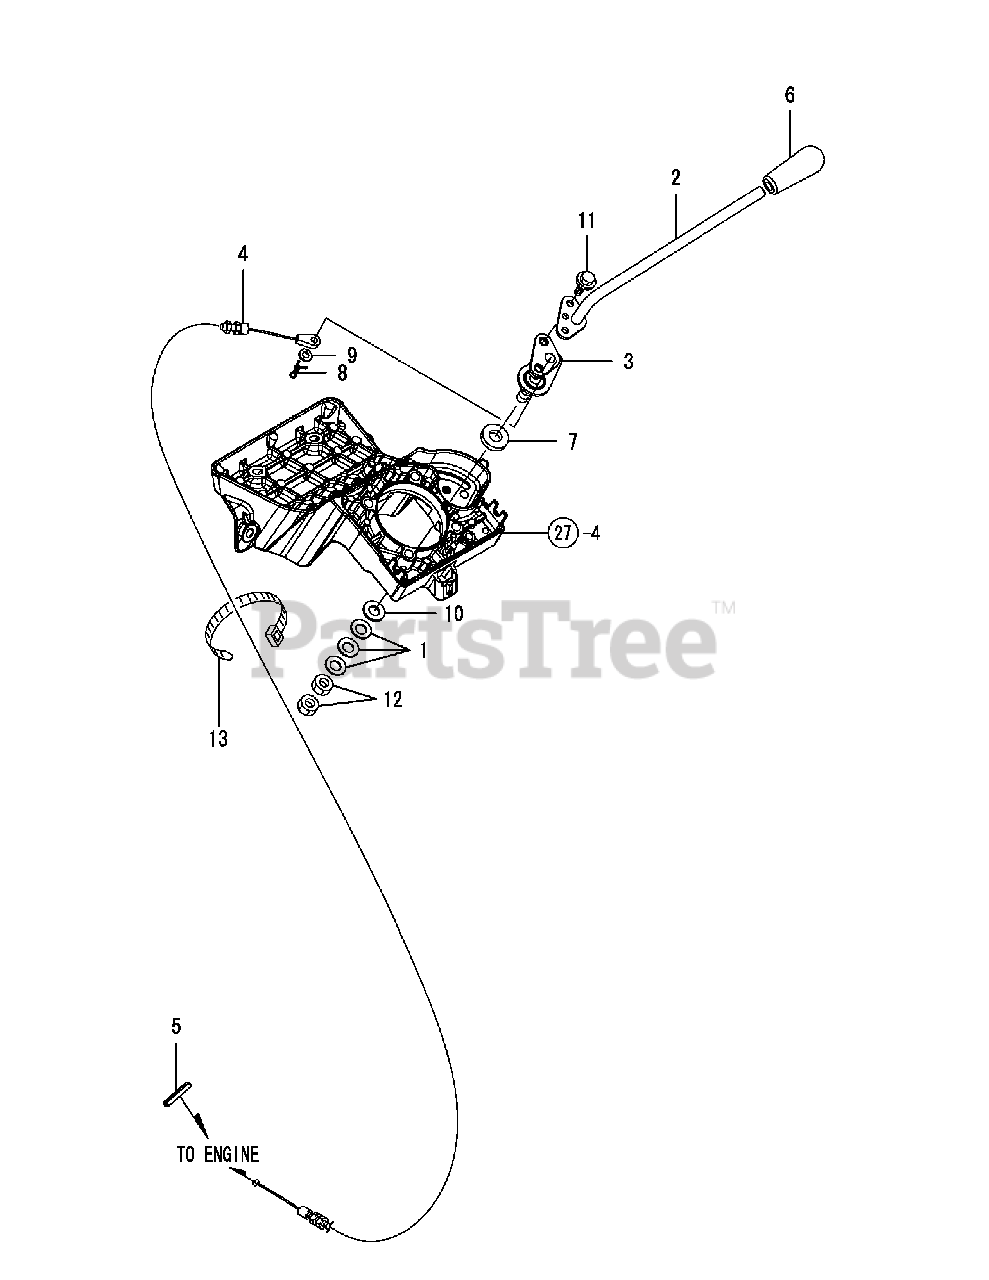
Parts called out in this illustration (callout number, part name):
1	WASHER 10, CONICAL
2	CONTROL LEVER, HEAD
3	CONTROL LEVER, BASE
4	CABLE ASSY, CONTROL
5	RUBBER,WIRE RETAING
6	KNOB, THROTTLE LEVER
7	SPACER 13X26X5
8	PIN 6, COME-OFF SNAP
9	WASHER 6, POLISHED
10	WASHER 10, POLISHED
11	BOLT M 6X 12 PLATED
